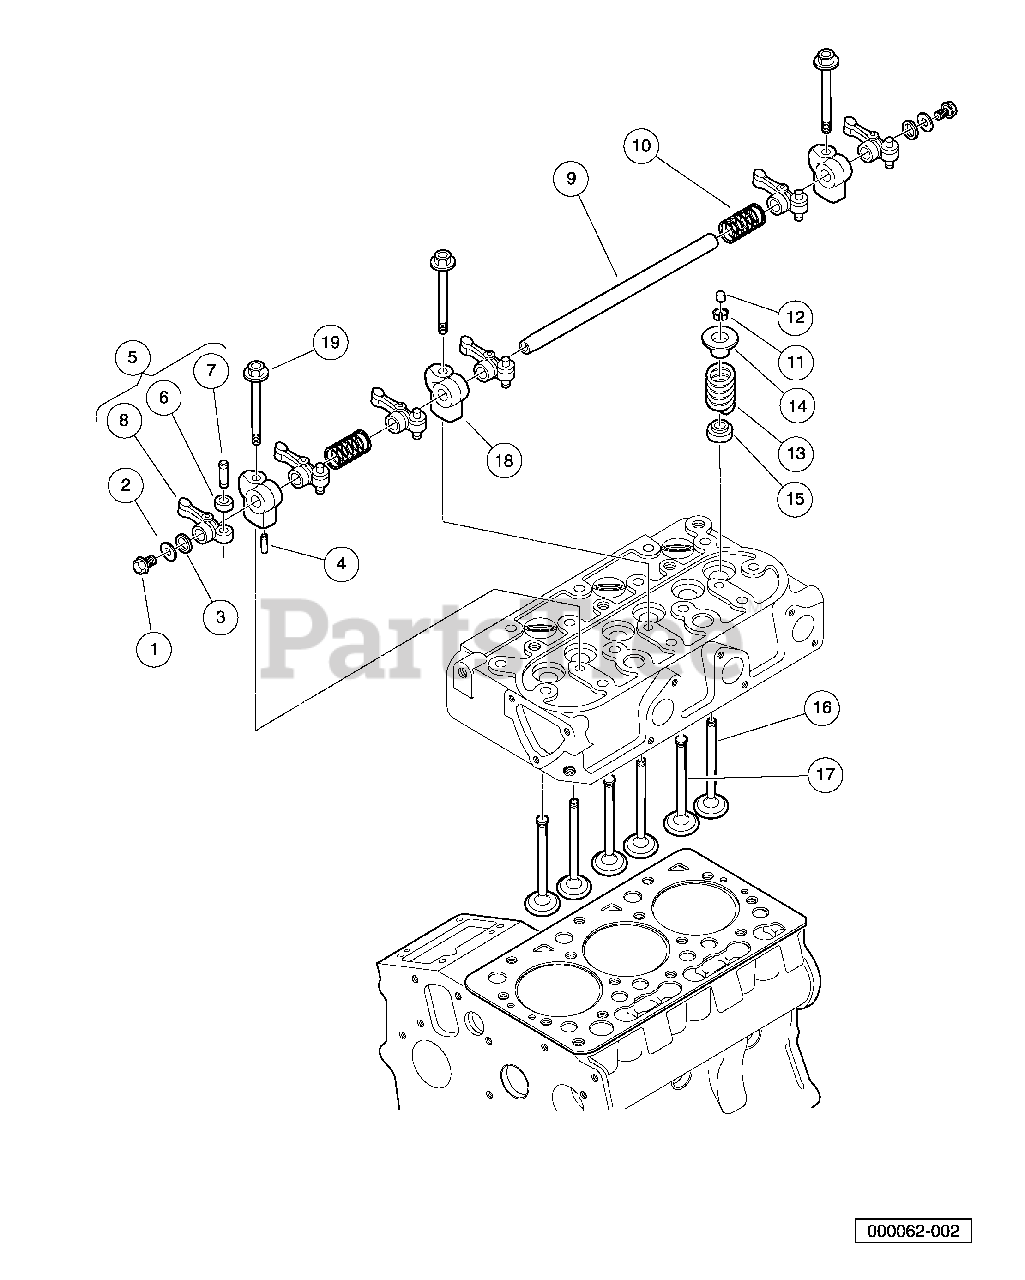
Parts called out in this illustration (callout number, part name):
1	Bolt, M6 X 1 X 8
2	Washer, D722, Plain, Rocker
3	Washer, Rocker Arm
4	Pin, Spring, D722, Rocker
5	Assy Rocker Arm
7	Screw-Adjusting
8	Arm, Rocker
9	Shaft, Rocker Arm
10	Spring, Rocker Arm
11	Collet, Valve Spring, Set
12	Cap, Valve, D722
13	Spring, Valve
14	Retainer, Spring
15	Seal, Valve Stem
16	Valve, Exhaust
17	Valve, Inlet
18	Bracket, Rocker Arm, D722 Closed-Breather
19	Bolt, Rocker Arm
